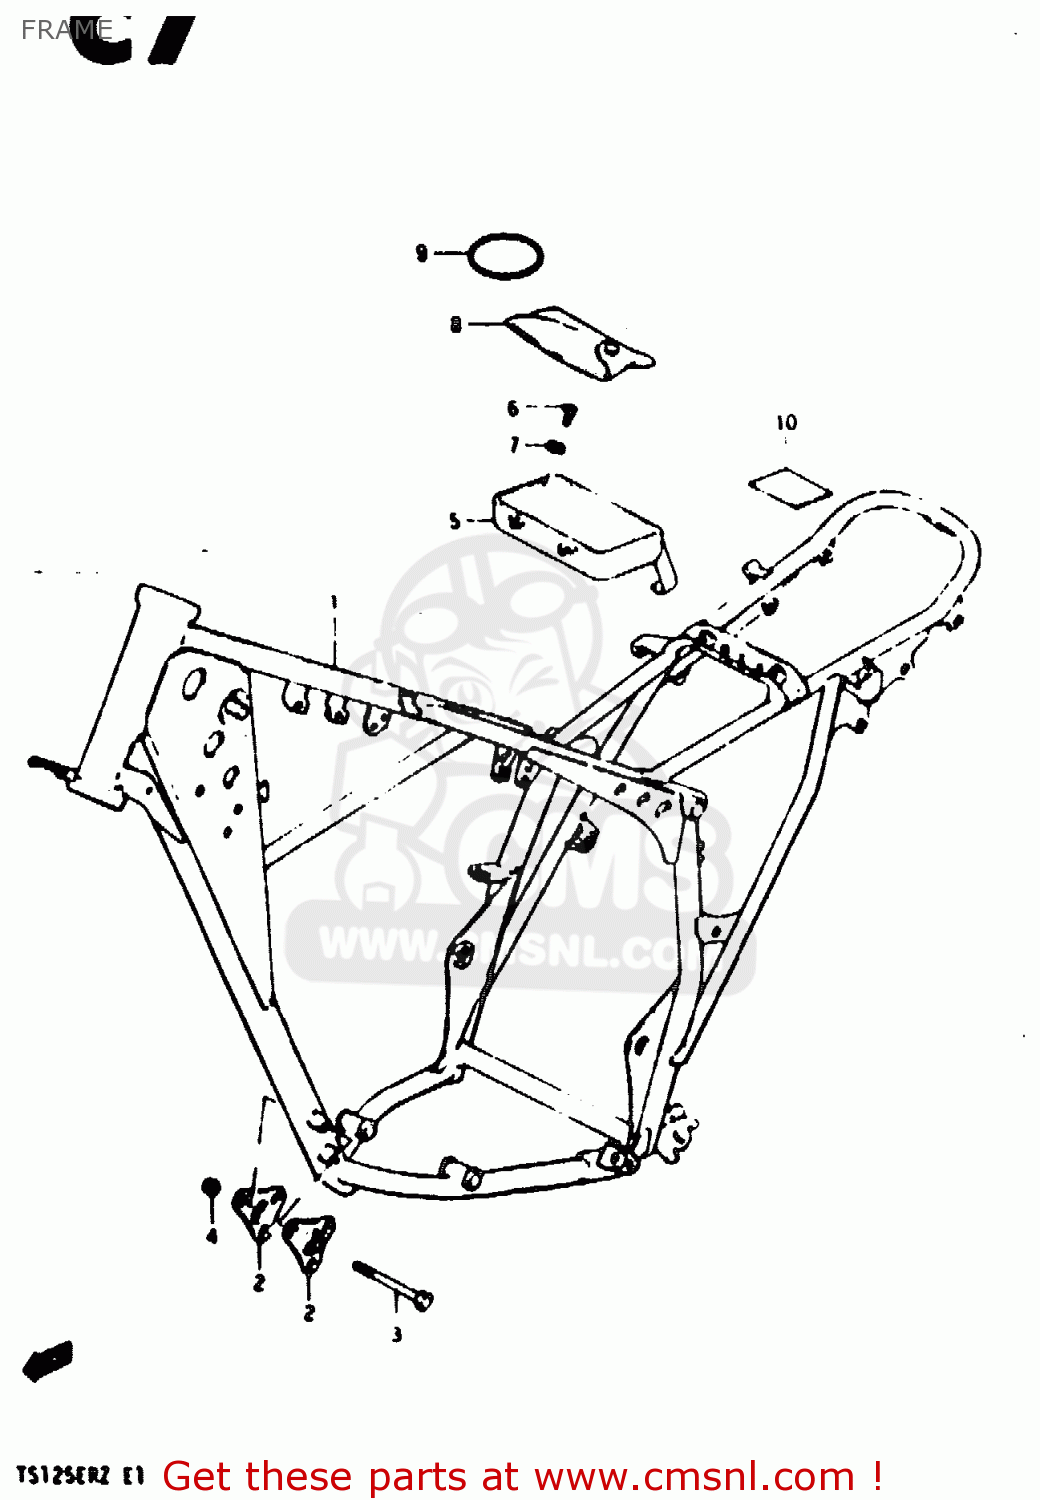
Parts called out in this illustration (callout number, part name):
1	FRAME (BLACK)
2	PLATE,ENG MTG
3	BOLT 8X65
4	NUT
5	HOLDER,TOOL
6	SCREW
7	WASHER (5.5X16X1.2)
8	TOOL SET
9	O RING(D:3.5,ID:76)
10	TAPE,TOOL BAG
